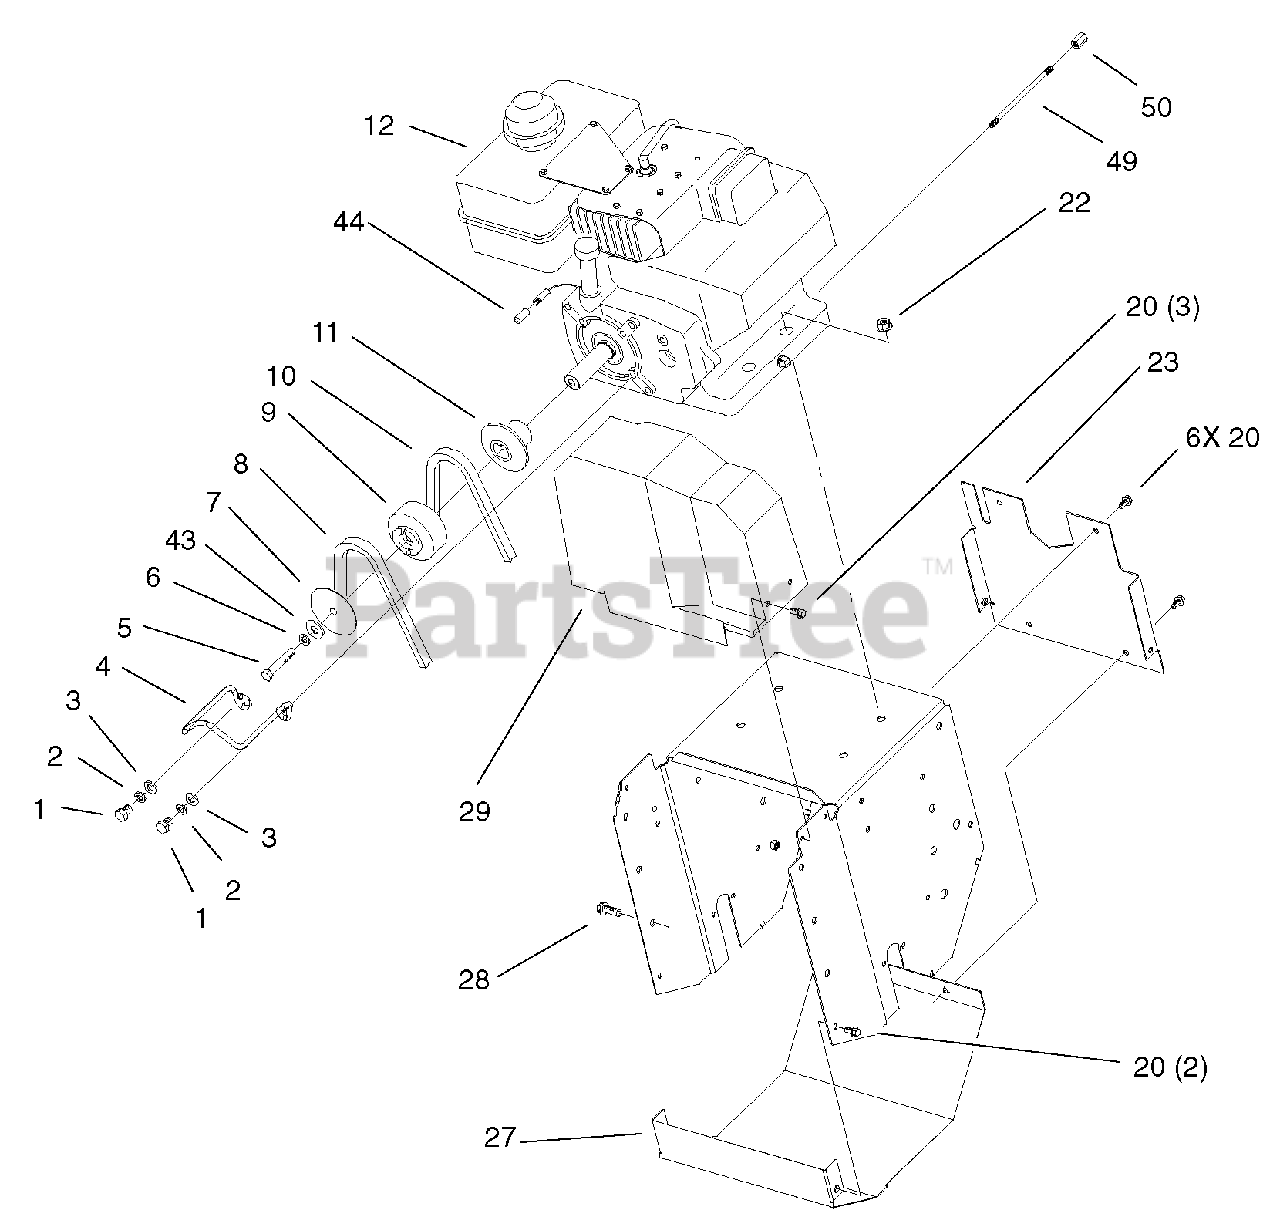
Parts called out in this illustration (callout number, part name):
1	Screw-HH
2	Washer-Lock
3	Washer-Flat
4	Guide-Belt
5	Screw-HH
6	Washer-Lock
7	Sheave-Half, Impeller
9	Pulley-Engine Center
10	V-Belt, Traction
11	Sheave-Half, Traction
20	Screw-HWH
23	Plate-Back
27	Cover-Lower Traction
28	Screw-HWH
29	Cover-Upper Belt
43	Washer-Flat
44	Cap-Wire, Lite
49	Nipple-Pipe
50	Cap-Pipe
